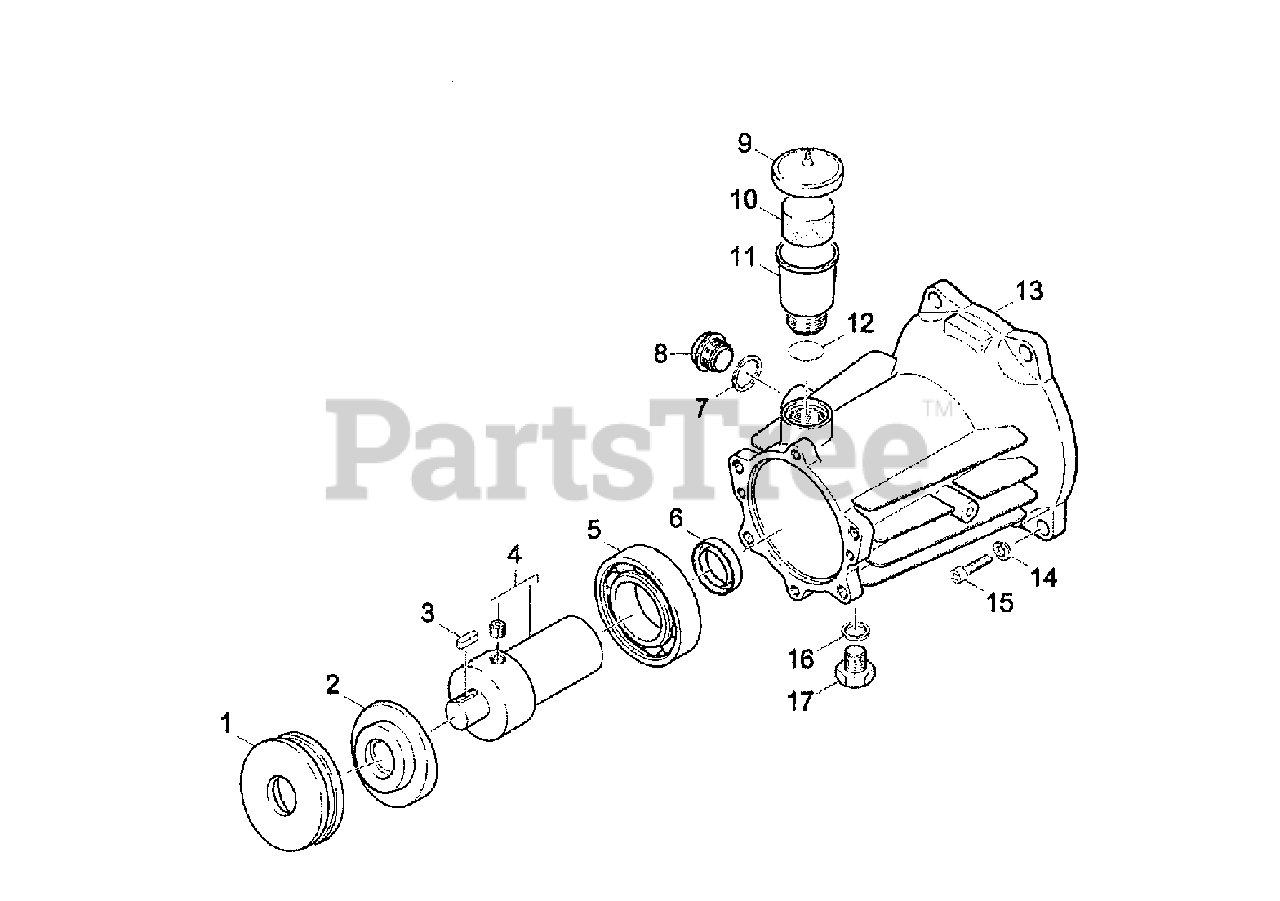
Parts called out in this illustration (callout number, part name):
1	Ball Bearing
2	Swash Plate
5	Ball Bearing
8	Closing Screw
17	Closing Screw
